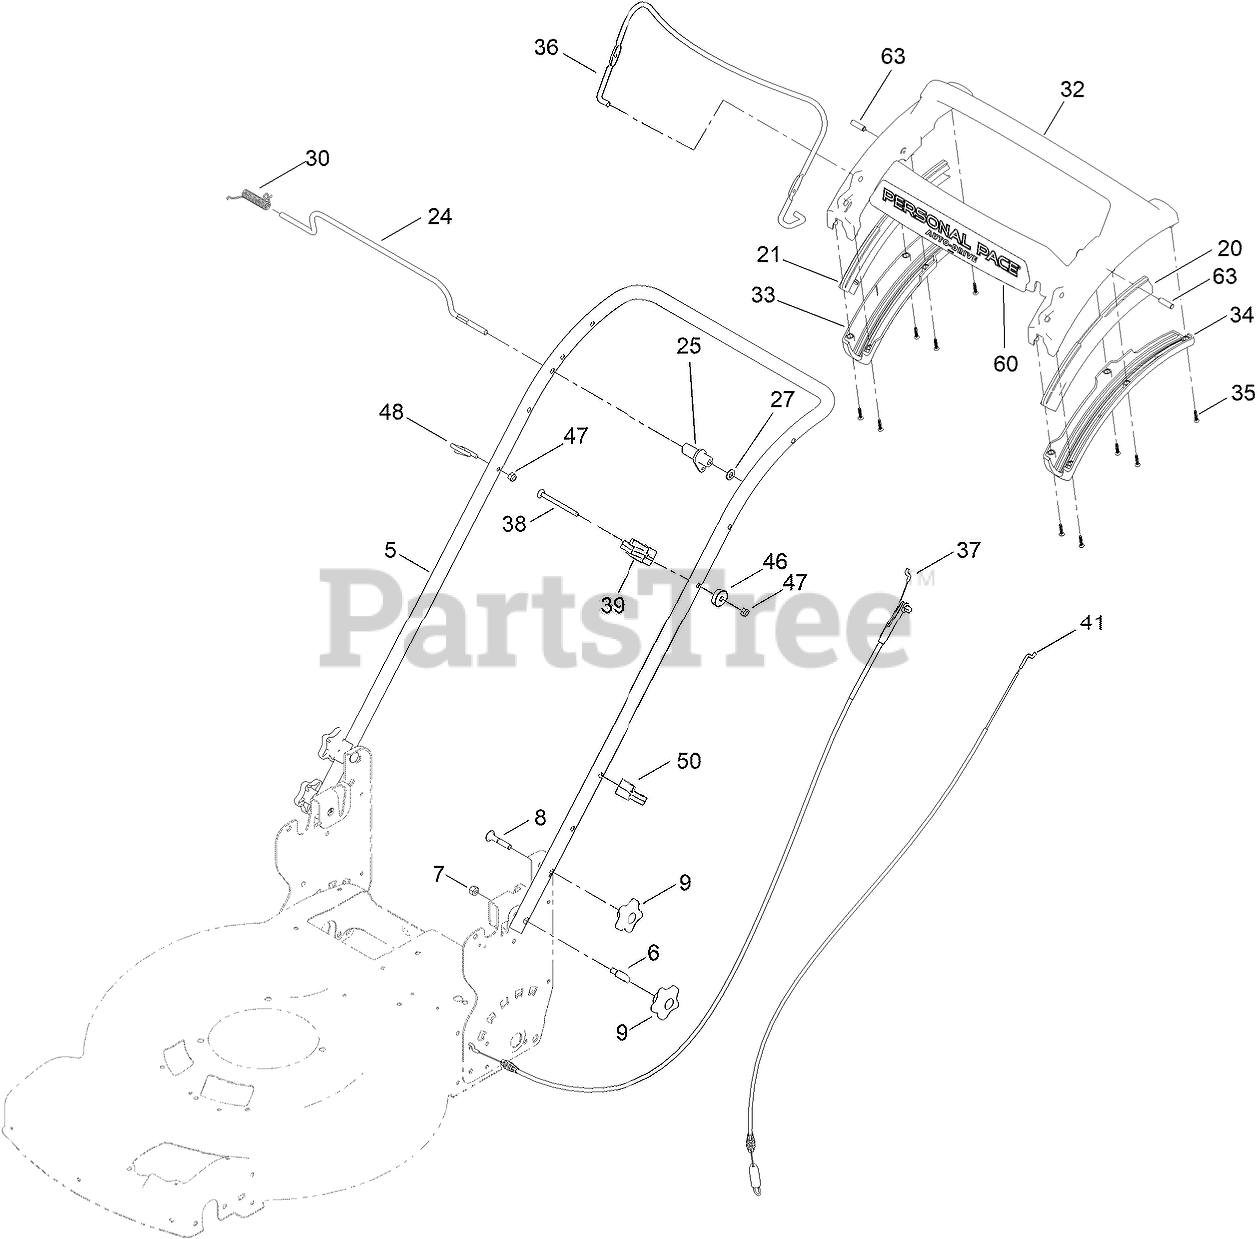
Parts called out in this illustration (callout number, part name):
5	HANDLE-CURVED
6	BOLT-SHOULDER, HANDLE
7	NUT-HEX
8	SCREW-CARR
9	KNOB-HANDLE
20	GUIDE-CURVED, LH (RWD)
21	GUIDE-CURVED, RH (RWD)
24	ROD-CONTROL, TRACTION
25	LEVER-TRACTION, RWD
27	WASHER-PLAIN
30	SPRING-TORSION
32	HANDLE-PERSONAL PACE, CURVED
33	BOTTOM-HANDLE, RH
34	BOTTOM-HANDLE, LH
35	SCREW-PPH
36	BAIL-BRAKE
37	CABLE-BRAKE, PP BS
38	SCREW-CARR
39	ANCHOR-CABLE, RWD
41	CABLE-TRACTION, RWD (PP)
46	WASHER-CURVED
47	NUT-HEX
48	GUIDE-ROPE
50	GUIDE-CABLE
60	DECAL - ADS, HANDLE
63	PIN-HANDLE, PP
